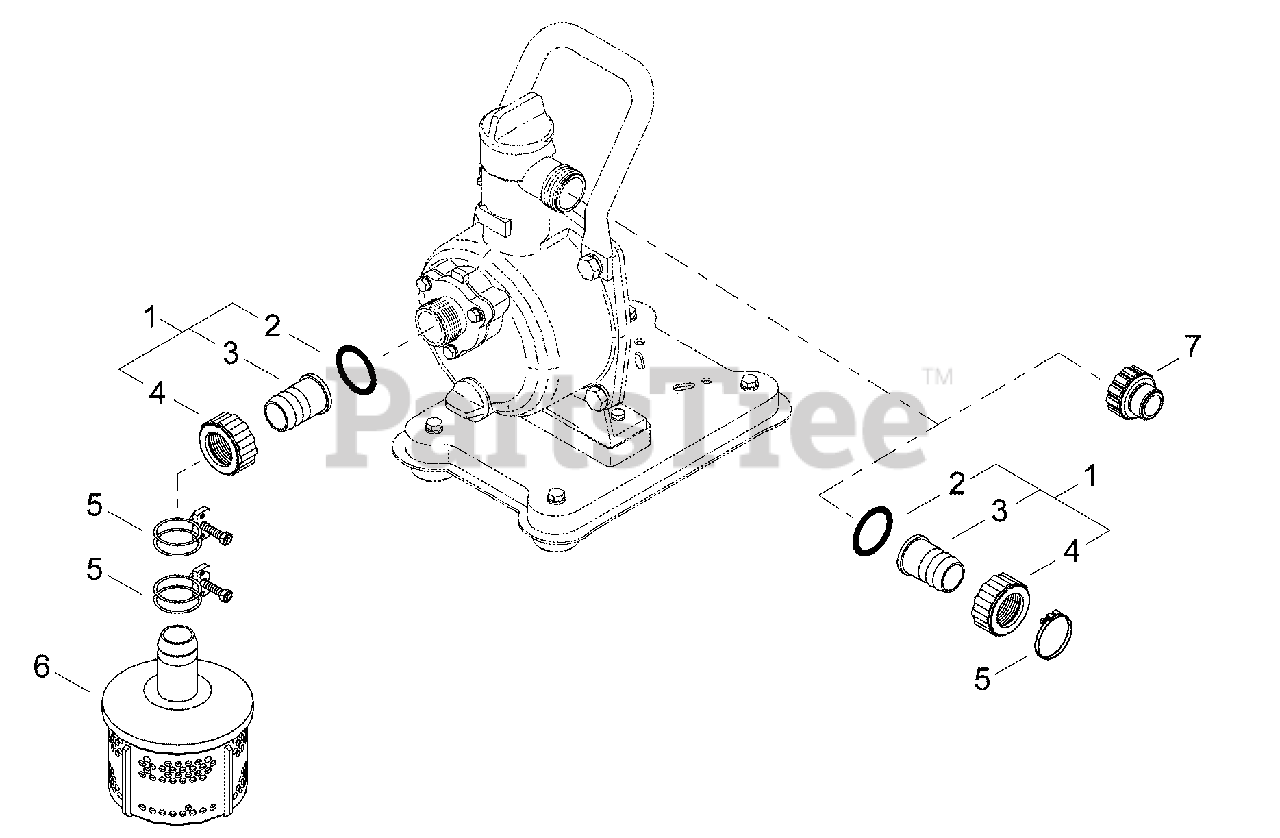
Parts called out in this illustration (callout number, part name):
1	HOSE COUPLING KIT
2	WASHER
3	COUPLING, HOSE
4	RINGNUT
5	CLAMP, HOSE
6	STRAINER, DEBRIS
7	ADAPTER, HOSE
